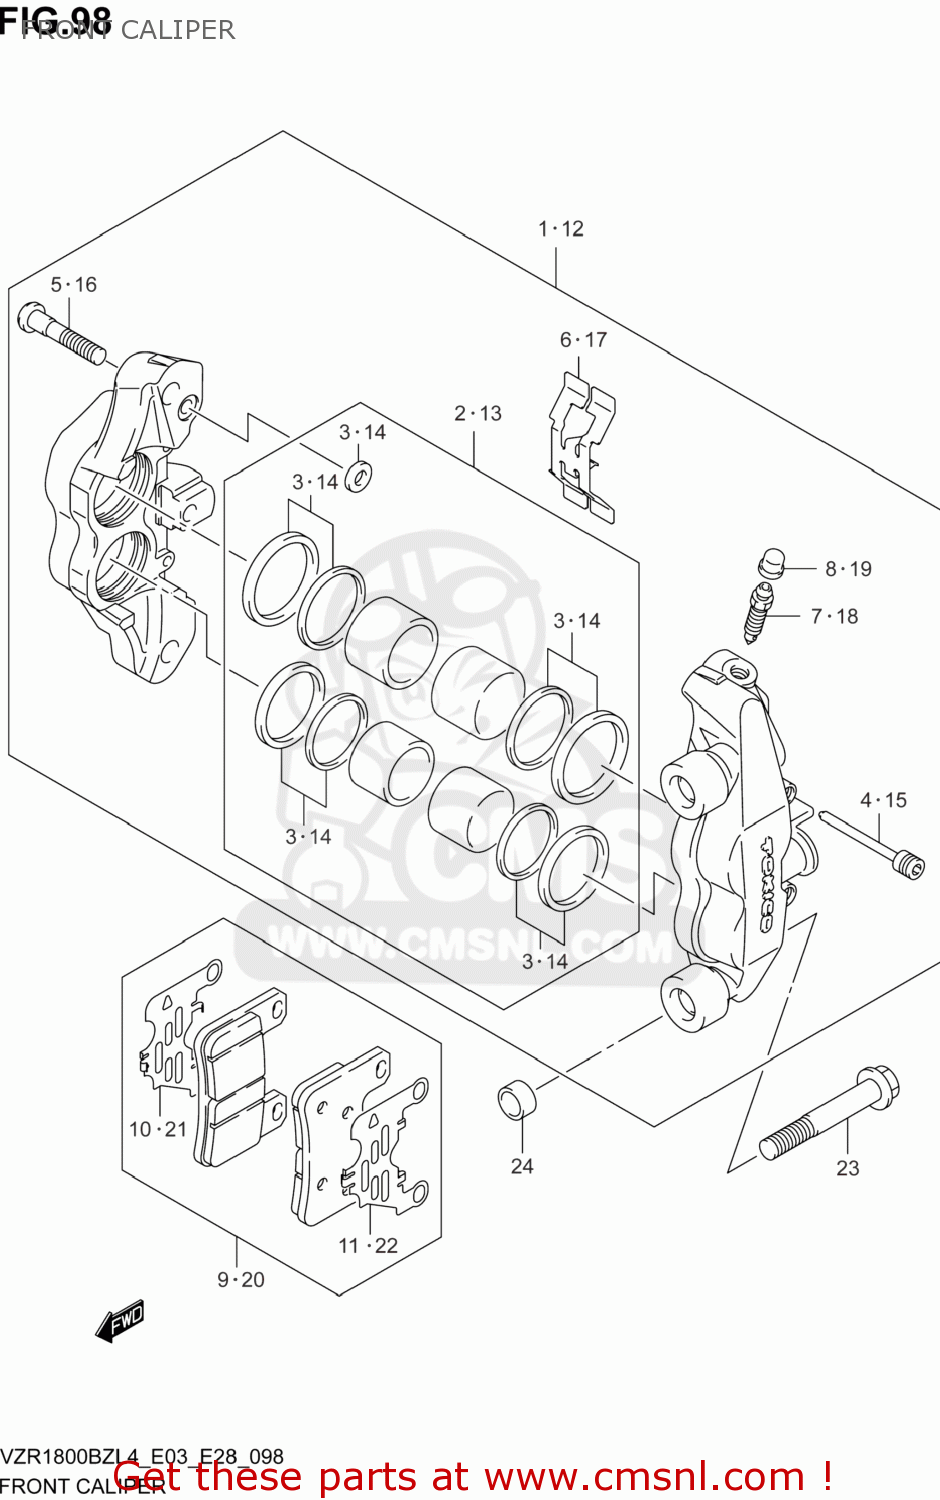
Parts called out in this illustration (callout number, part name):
1	CALIPER ASSY,FRONT RH
2	PISTON SET
3	SEAL SET,PISTON
4	PIN
5	BOLT
6	SPRING,PAD
7	BLEEDER
8	CAP,BLEEDER PLUG
9	PAD & SHIM SET (NAS)
10	SHIM,PAD A
11	SHIM,PAD B
12	CALIPER ASSY,FRONT LH
13	PISTON SET
14	SEAL SET,PISTON
15	PIN
16	BOLT
17	SPRING,PAD
18	BLEEDER
19	CAP,BLEEDER PLUG
20	PAD & SHIM SET (NAS)
21	SHIM,PAD A
22	SHIM,PAD B
23	BOLT(10X70)
24	PIN,CALIPER
